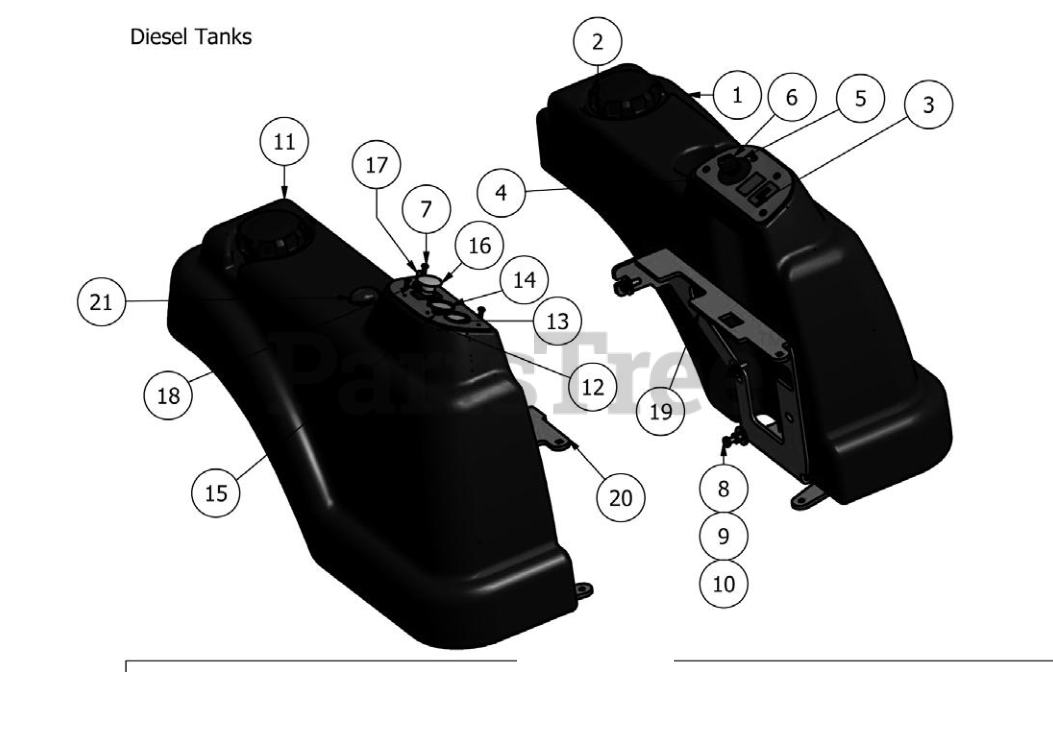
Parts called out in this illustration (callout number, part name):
1	Left Fuel Tank
2	Diesel Fuel Cap
3	Hourmeter-Diesel
4	Control Panel (Left)
5	Ignition Switch
6	Ignition Key
7	10-32x 3/8" Button Socket
8	5/16" x 1" Hex Bolt
9	5/16" Lock Washer
10	5/16" Flat Washer
11	Right Fuel Tank
12	Diesel Control Panel (Right)
13	Oil Guage With Sender
14	Temperature Guage With Sender
16	PTO Engager
17	Deck Lift Joystick
18	Joystick Cover
19	Tank Support-Left
20	Tank Support-Right
21	Fuel Gauge & Grommet
